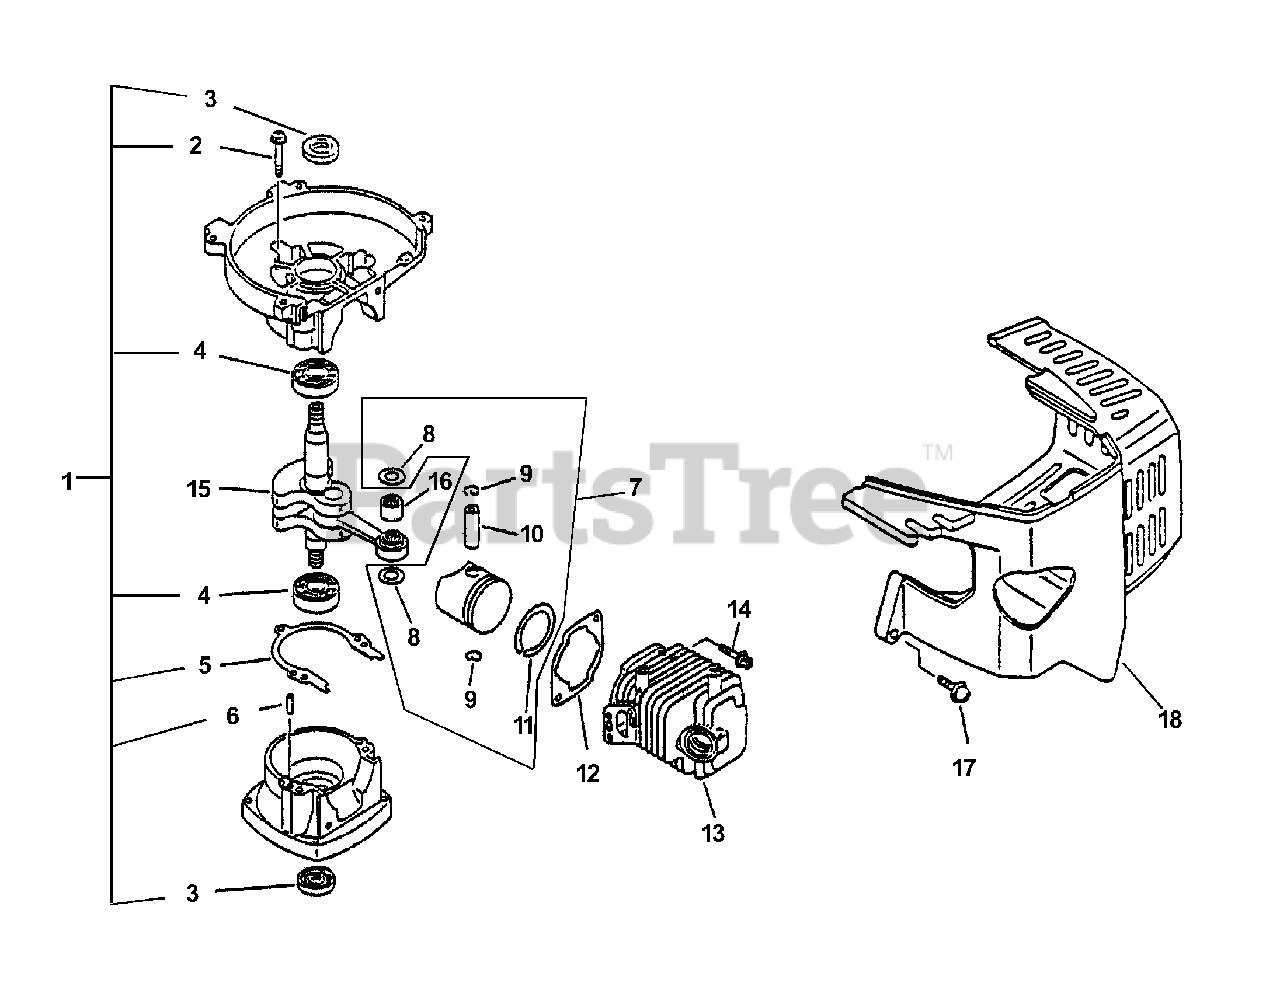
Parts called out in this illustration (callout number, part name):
1	CRANKCASE KIT
2	SCREW - 5X28
3	SEAL, OIL
4	BEARING, BALL - 6201
5	GASKET, CRANKCASE
6	PIN - LOCATING
7	PISTON KIT
8	SPACER, PISTON
9	RING, RETAINING
10	PIN, PISTON
11	RING, PISTON
12	GASKET, CYLINDER
13	CYLINDER
14	SCREW - 5X22
15	CRANKSHAFT ASSY
16	BEARING, NEEDLE
17	SCREW - 4X20
18	COVER, ENGINE
